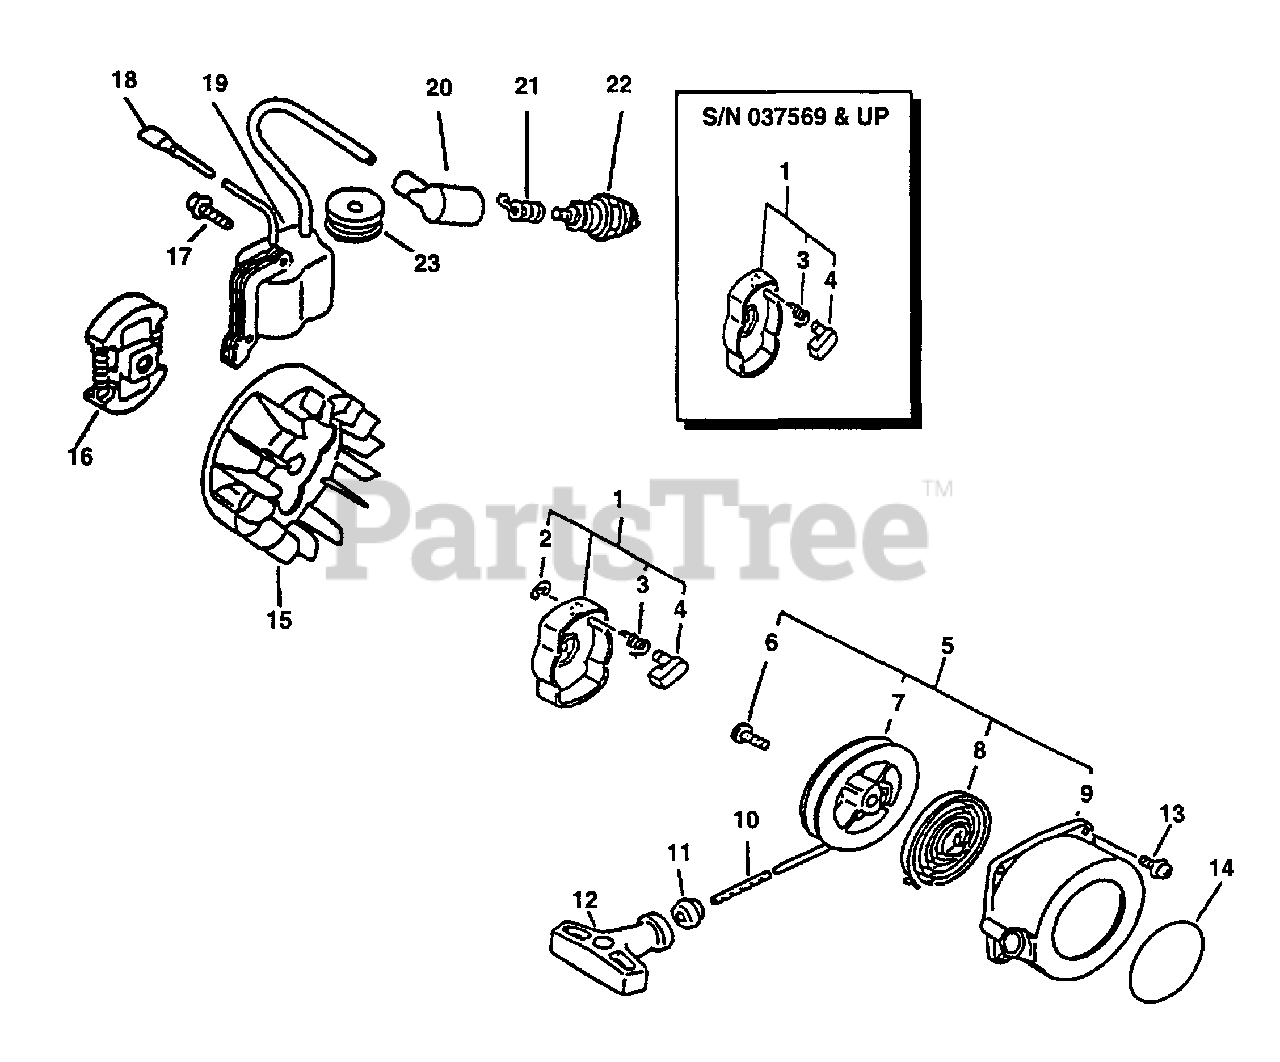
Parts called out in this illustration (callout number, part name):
1	STARTER PAWL ASSY
1	PAWL ASSY, STARTER
2	E-RING 4
3	SPRING, RETURN
4	PAWL, STARTER
4	PAWL, STARTER - BLACK
5	STARTER ASSY
6	SCREW
7	REEL, ROPE
8	SPRING, RECOIL
9	CASE, RECOIL STARTER
10	ROPE, STARTER
11	GUIDE, ROPE
12	GRIP, STARTER
13	BOLT 4×16
14	LABEL, ECHO
15	FLYWHEEL
16	CLUTCH ASSY
17	SCREW 4×22
18	LEAD - GROUND
19	COIL, IGNITION
20	CAP, SPARK PLUG
21	TERMINAL, SPARK PLUG
22	SPARK PLUG - BPM7A
23	GROMMET
